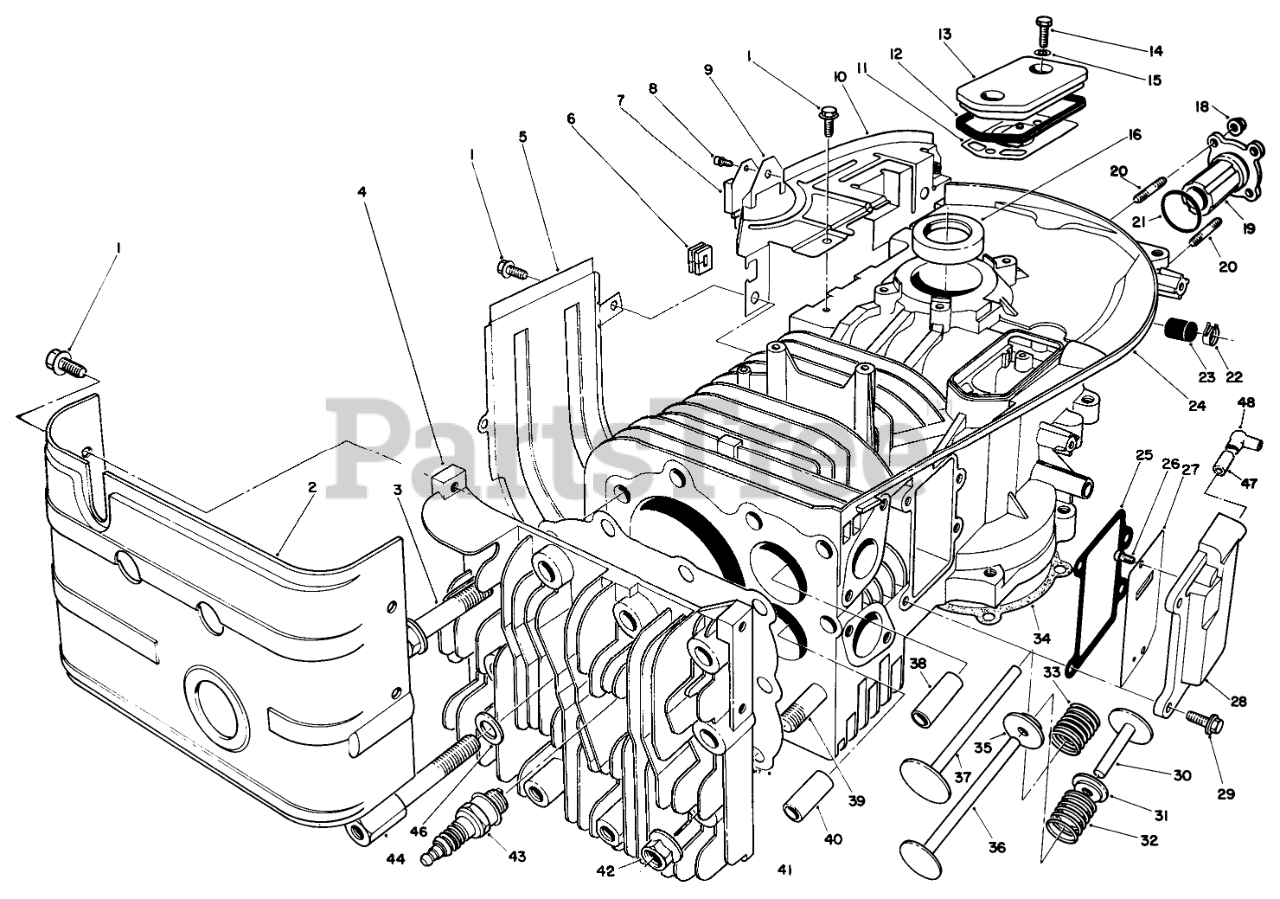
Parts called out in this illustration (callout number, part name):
1	Bolt-Flanged (6X10)
3	Bolt
4	Cylinder Head
7	Igniter
10	Fan Housing
14	Bolt
18	Nut
19	Shaft
24	Crankcase Assembly
28	Cover-Valve Chamber
29	Bolt-Flanged (6X16)
31	Retainer-Spring
32	Spring-Valve
33	Spring-Valve
36	Exhaust Valve
37	Intake Valve
38	Guide-Intake Valve
40	Guide-Exhaust Valve
41	Gasket
43	Spark Plug
46	Washer
